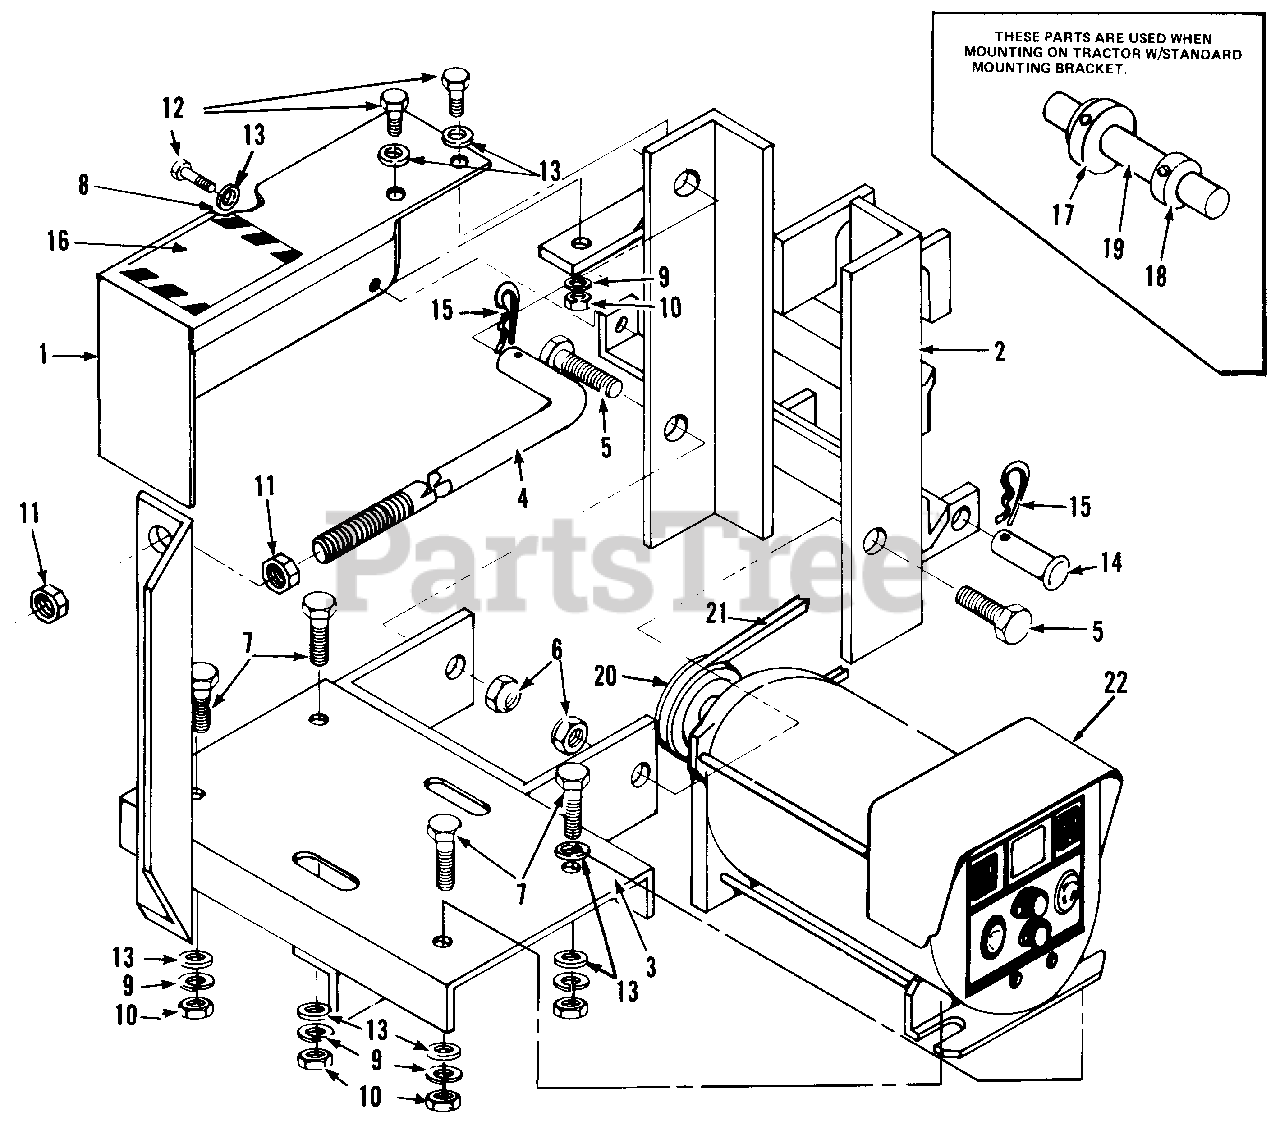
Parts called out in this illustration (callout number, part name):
1	GUARD, Belt
2	BRACKET, Tractor Mounting
3	BRACKET, Alternator Mounting
4	ROD, Belt Tension
5	CAPSCREW, 1/2-13 x 1-1/4
6	LOCKNUT, Hex, 1/2-13
7	CAPSCREW, 5/16-18 x 1
8	DECAL, Simplicity
9	LOCKWASHER, 5/16
10	NUT, Hex, 5/16-18
11	NUT, Hex, 1/2-13
12	CAPSCREW, 5/16-18 x 3/4
13	WASHER, Plain, 5/16
14	PIN, 7/16 x 1-3/4
16	DECAL, Warning
17	COLLAR, Set
18	COLLAR, Set
19	SHAFT, Support
21	V-BELT
22	ALTERNATOR
